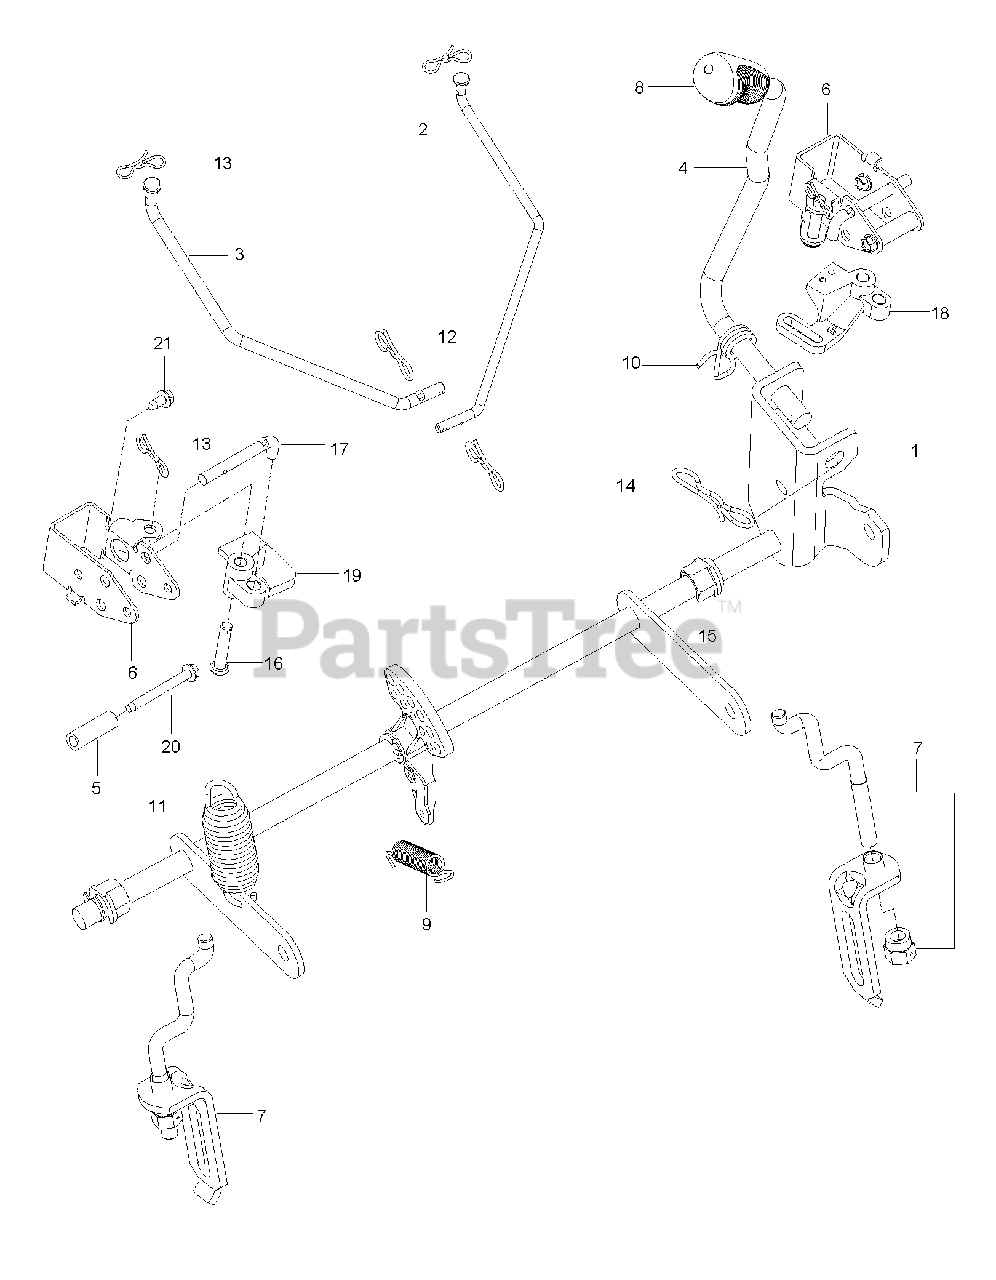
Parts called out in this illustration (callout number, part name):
1	SHAFT.ASM.RZ.DECK.LIFT.SRV
2	LINK.BRAKE.PARK.UPPER.LH
3	LINK.BRAKE.PARK.UPPER.RH
4	LIFT.LEVER.ASM.RZ.SERVICE
5	SPACER.334.ID.5.OD.1.5.L
6	BRACKET.BELLCRANK.PBRAKE X431
7	LINK.ASM.RZ.LIFT.SERVICE
8	GRIP.HANDLE.LIFT.PVC.428
9	RETURN.BRAKE.PARK.AUTO
10	SPRING.TORSION.LIFT.HANDLE
12	PIN.COTTER.5/16.BOW TI
13	PIN COTTER;LOCKING;BOWTIE;1IN
14	PIN.COTTER.7/16.BOW TI.
15	PLASTIC NUT
16	PIN.5.16X1.5
17	ROD.PUSH.BRAKE
18	BELLCRANK.LH
19	BELLCRANK.RH
20	SCREW THD;ROLL;1/4-20 X 2.25
21	SCREW.1/4-20X5/8
